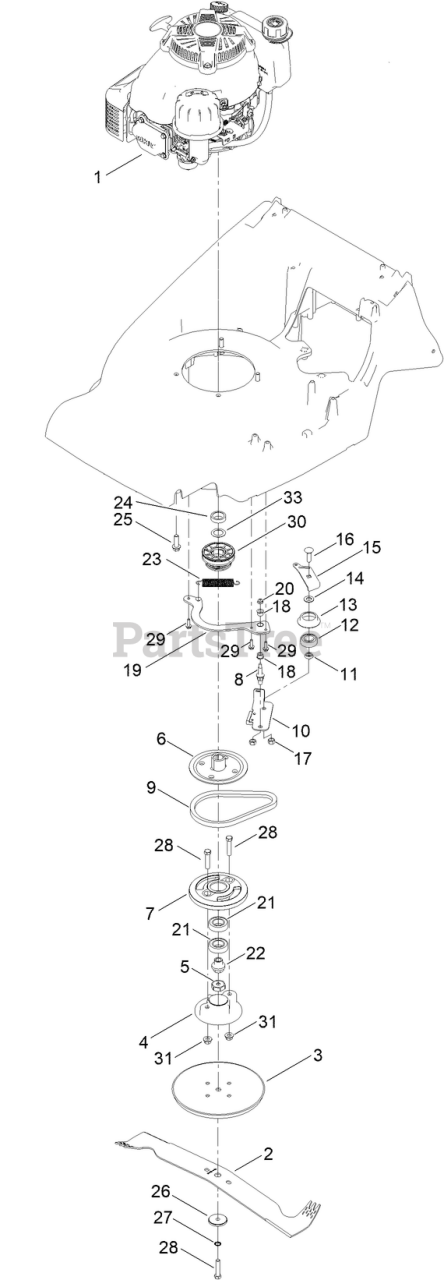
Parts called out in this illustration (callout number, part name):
2	CUTTERBAR, 56CM
3	DISC-FRICTION
4	SPACER-BLADE, BBC
5	NUT-RETAINING
6	PULLEY HALF DRIVE BBC
7	DRUM-BBC
8	BOLT-SHOULDER
10	PLATE-BRAKE
11	SPACER-BEARING
12	BEARING-BALL
13	RETAINER-BELT
14	SPACER
15	PLATE-TENSIONER
16	SCREW-CARR
17	LOCKNUT
18	BUSHING-FLANGE
19	BBC ANCHOR PLATE ASSY
20	NUT-HF
21	BEARING
22	BBC SHAFT NUT
23	SPRING-TENSION, BRAKE
24	SPACER-RETAINING
25	SCREW-TAPTITE, UNC
26	SPACER-DISTANCE, CUTTERBAR
27	WASHER-LOCK
28	BOLT, UNF 3/8 X 1.3/4 (GRADE 8. ROHS)
29	SCREW-TAPTITE
30	PULLEY-ENGINE
31	NUT-FLANGE, LOCK
33	SPRING-DISK
